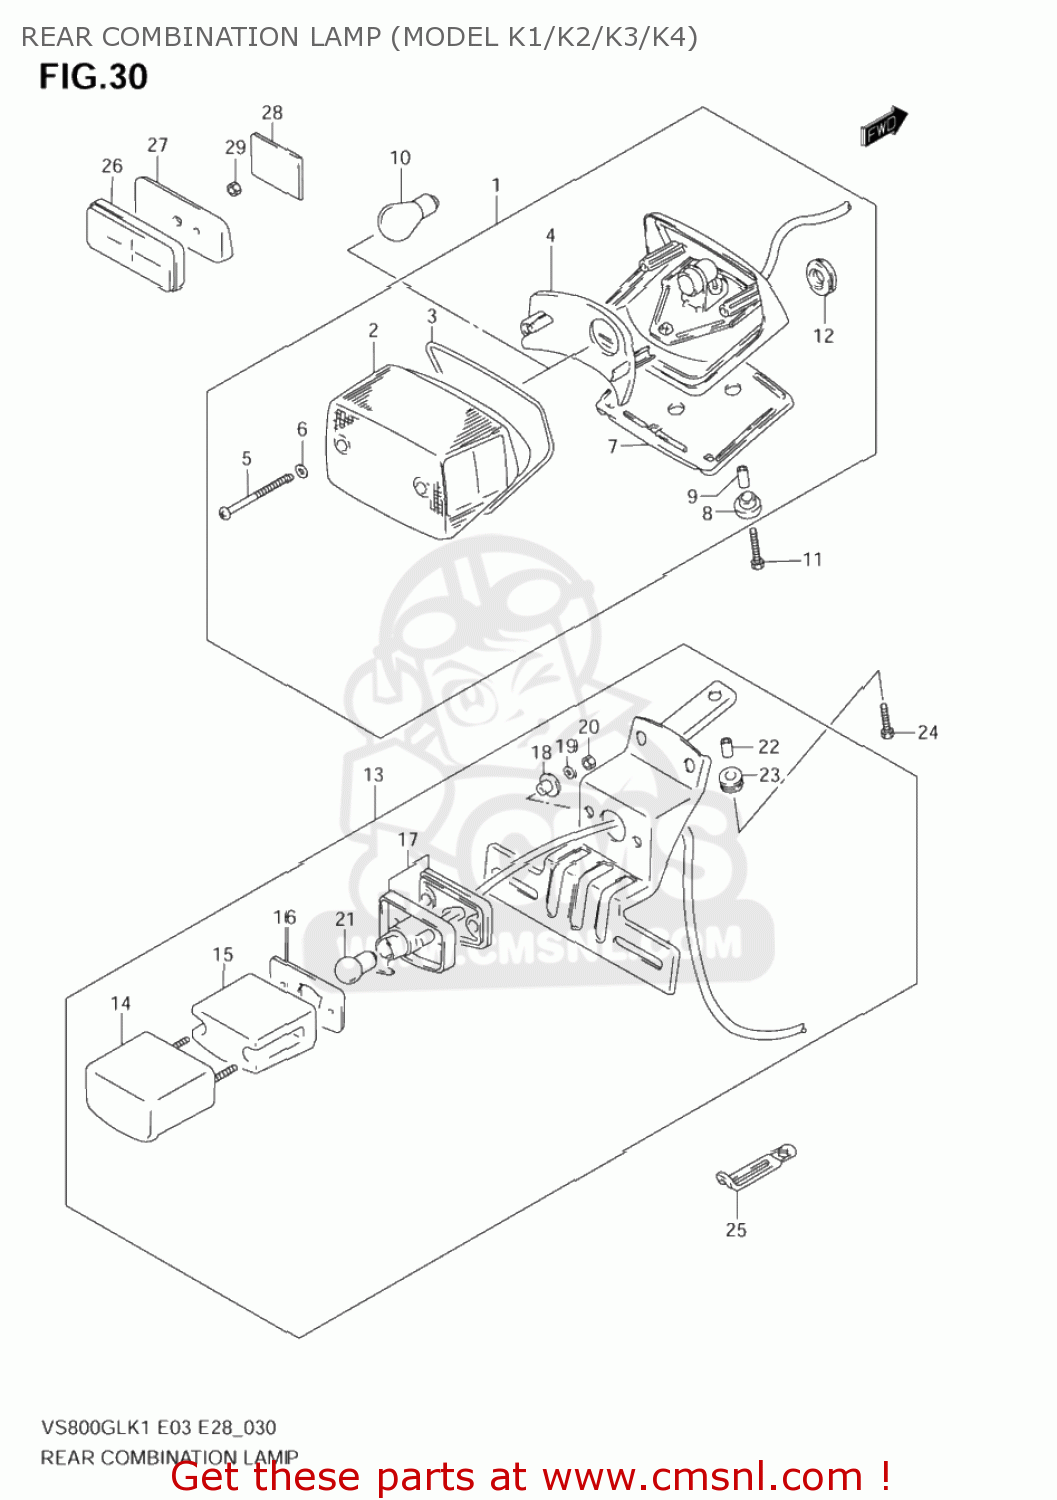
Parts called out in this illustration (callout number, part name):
1	LAMP ASSY,RR COMBINATION
2	LENS
3	GASKET (NAS)
4	REFLECTOR
5	SCREW
6	GASKET (NAS)
7	CUSHION
8	CUSHION
9	SPACER
10	BULB(12V21/5W)
11	BOLT(6X25)
12	GROMMET
13	LAMP ASSY,LICENSE
14	COVER,LICENSE LAMP
15	LENS
16	GASKET,LICENSE LAMP (NAS)
17	HOUSING,LICENSE LAMP
18	SPACER
19	WASHER,LOCK
20	NUT
21	BULB(12V8W)
22	SPACER
23	CUSHION
24	BOLT(6X20)
25	CLAMP(L:45)
26	REFLECTOR ASSY,RR
27	SPACER,RR REFLECTOR
28	TAPE,TOOL BAG PROTECTOR
29	NUT
